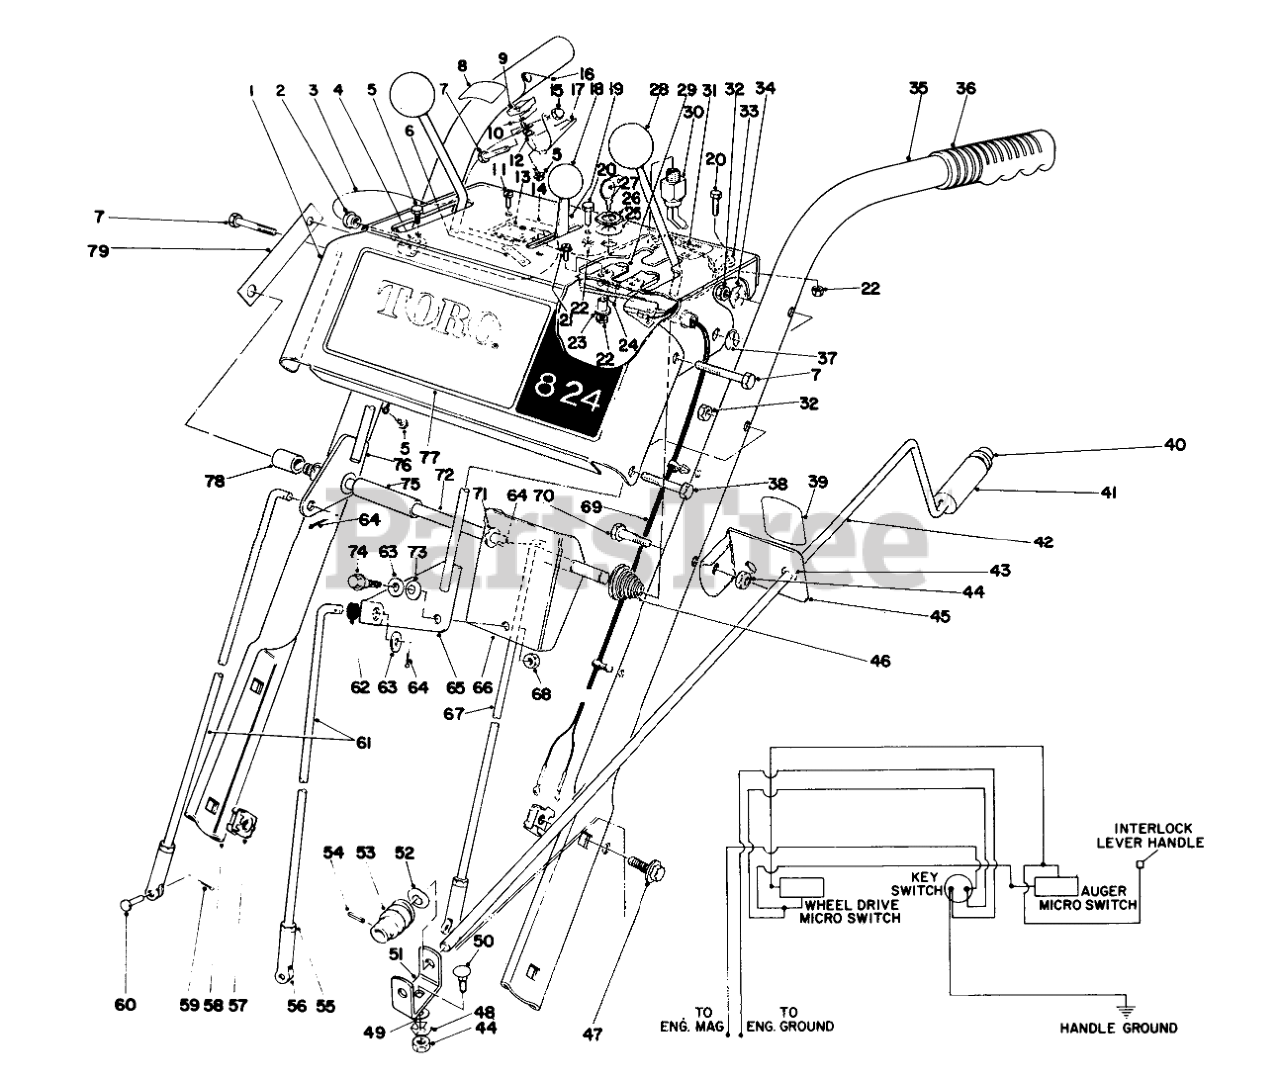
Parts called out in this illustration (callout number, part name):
1	Escutcheon
2	Snap Bushing
3	Wire Assembly
4	PLASTIC CLIP
5	SCREW
6	NUT-SPEED
7	SCREW-HH
8	INTERLOCK DECAL
9	Insulator
10	INTERLOCK CONTACT
11	SCREW-SPH
12	WASHER INSULATOR
13	MICRO SWITCH
14	SWITCH MTG PAD
15	NUT-CAP
16	INTERLOCK SPRING
17	SAFETY INTRLOCK LEVER
18	CONTROL KNOB
19	THROTTLE CONTROL
20	HEX HEAD SEMS 10-24X1/2
21	SCREW-SRH
22	Nut
23	INTERLOCK SPACER
24	INTERLOCK SPRING
25	WASHER-TOOTH, INTERNAL
26	NUT-HH
27	Key
29	Slide Interlock
30	SWITCH-ON / OFF
31	INSTRUCTION DECAL
33	CABLE CLAMP
34	Washer
35	LEFT HANDLE
36	Grip Handle
37	RING-CLIP
38	SCREW-HH
39	CHUTE DECAL
40	RETAINER-PUSH ON
41	GRIP-CONTROL, CHUTE
42	CHUTE CONTROL ROD
43	Bushing
44	NUT-LOCK, NI
45	Chute Control Rod Mounting (Incl. Ref. #39 & 43)
46	CONICAL SPRING
47	SCREW-HHF
48	WASHER-LOCK
49	WASHER
50	BOLT-CARR
51	WORM BRACKET
52	WASHER-SPRING
53	GEAR-WORM, CHUTE
54	PIN-SPRING
55	NUT-HJ
56	CLEVIS
57	Retained Nut
58	RIGHT HANDLE
59	PIN-COTTER
60	PIN-CLEVIS
61	SPEED SELECTOR ROD
62	GROMMET-RUBBER
63	WASHER-FLAT
64	PIN-COTTER
65	SHIFT LEVER WA
66	SHIFT BRACKET
67	TRACTION CONTROL ROD
68	NUT-LOCK, CONE
69	Wire Harness Interlock
70	SCREW-HH
71	WASHER-FLAT
72	PIVOT ROD
73	7/16 SPRING WASHER
74	SHOULDER SCREW
75	SHIFT LEVER SPACER
76	LEVER WA
77	ESCUTCHEON DECAL
78	AUGER LEVER SPACER
79	ESCUTCHEON SUPT STRAP
